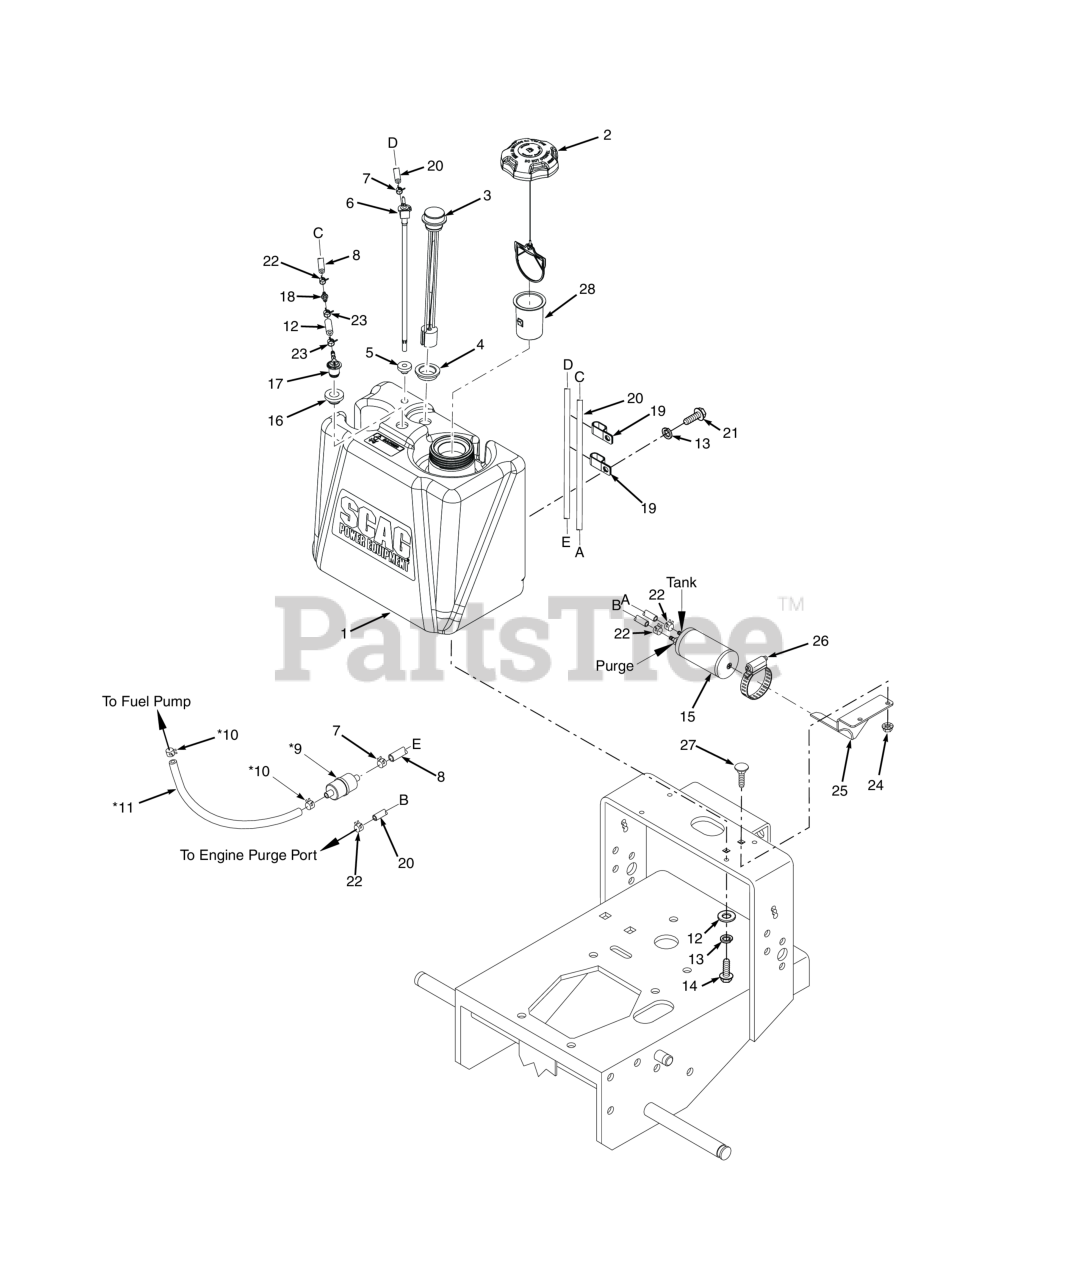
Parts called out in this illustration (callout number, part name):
1	Fuel Tank Assembly (incl. #3, 4, 5, 6, 16, 17)
2	Fuel Cap w/ Tether (E.P.A.)
3	Fuel Gauge Assembly
4	Grommet, Fuel Gauge
5	Bushing, 0.56" Dia. Viton
6	Valve, Fuel Shutoff w/Screen
7	Clamp, Fuel Hose 1/4" Hose I.D.
8	Fuel Hose, 1/4" I.D. Non-Perm (791DFI Fuel Return) - Order by Inch
9	Fuel Filter
10	Clamp, Fuel Hose
11	Fuel Hose
12	Hose, 1/4" Vapor Recovery (order by inch)
13	Lockwasher, 5/16 (.317 x .586 x .078) Helical Spring
14	Bolt, Heax Head 5/16-18 x 1" (48V / 52V)
15	Carbon Canister - SVR-36A / SVR-48V
16	Grommet, Viton,
17	Remote Vent, No Valve
18	Mender, 1/4 x 3/16 w/0.02 Hole
19	Clamp, Double Cable 5/8" ID.
20	Hose, Vapor Recovery 3/16" (order by inch)
21	BOLT, SERRATED FLANGE HEX HEAD 5/16-18 X 3/4"
22	Clamp, Vapor Recovery Hose 3/16"
23	CLAMP, FUEL HOSE(KAWASAKI ONLY)
24	Nut, Serrated Flange 5/16-18 (Right Front Engine Mounting, Briggs and Kohler Only)
25	Bracket, Canister Mounting
26	Clamp, 3-1/2" Max. Dia.
27	Bolt, Carriage 5/16-18x1" (large frame units only)
28	Tube, Fuel Tank Insert - 4"
